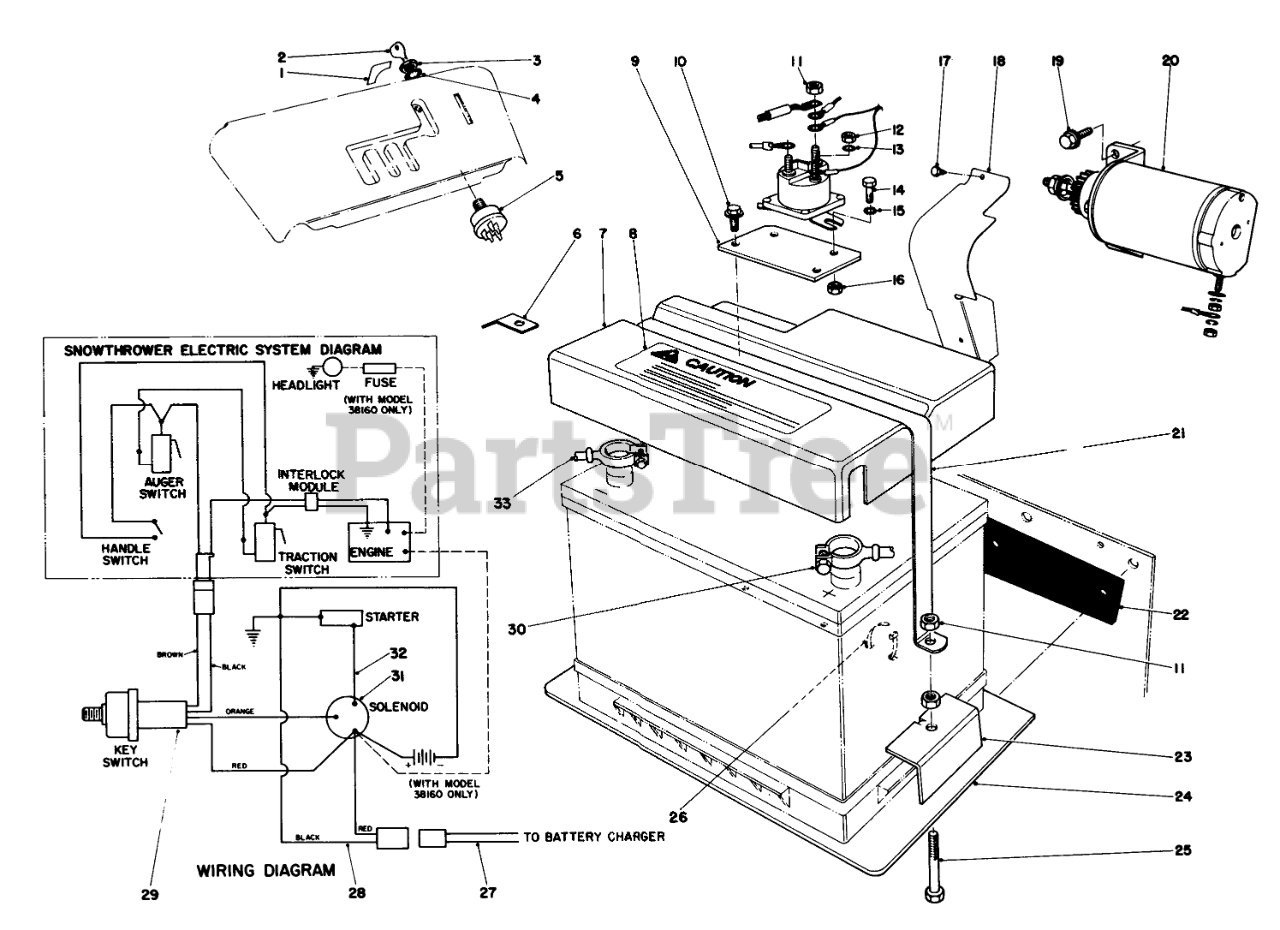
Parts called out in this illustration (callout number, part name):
1	Decal Switch
2	Key
3	NUT-HH
4	WASHER-TOOTH, INTERNAL
5	SWITCH-STARTER
6	Bracken Wire Clamp
7	Battery Cover (Incl. Ref. #8)
8	Decal-Caution
9	Bracket Solenoid
10	SCREW-HWH
11	NUT-HEX
12	NUT-HEX
13	WASHER-LOCK, INT
14	SCREW-HH
15	WASHER-LOCK/EXT
16	NUT-LOCK, NI
17	Hex Hd. Sems Screw
18	Pinion Shield
19	Screw-HH
20	Starter Motor & Pinion Assy.
21	Strap Battery
22	Batery Isolation Pad
23	BATTERY CLAMP
24	Battery Mounting Plate
25	SCREW-HH
26	TIE-CABLE
27	MALE WIRE ASM
28	FEMALE WIRE ASM
29	12 V IGN WIRE HARNESS
30	BATT-SOLENOID CABLE
31	SOLENOID
32	STRT MTR-SOLNOID WIRE
33	BATT-GROUND CABLE
